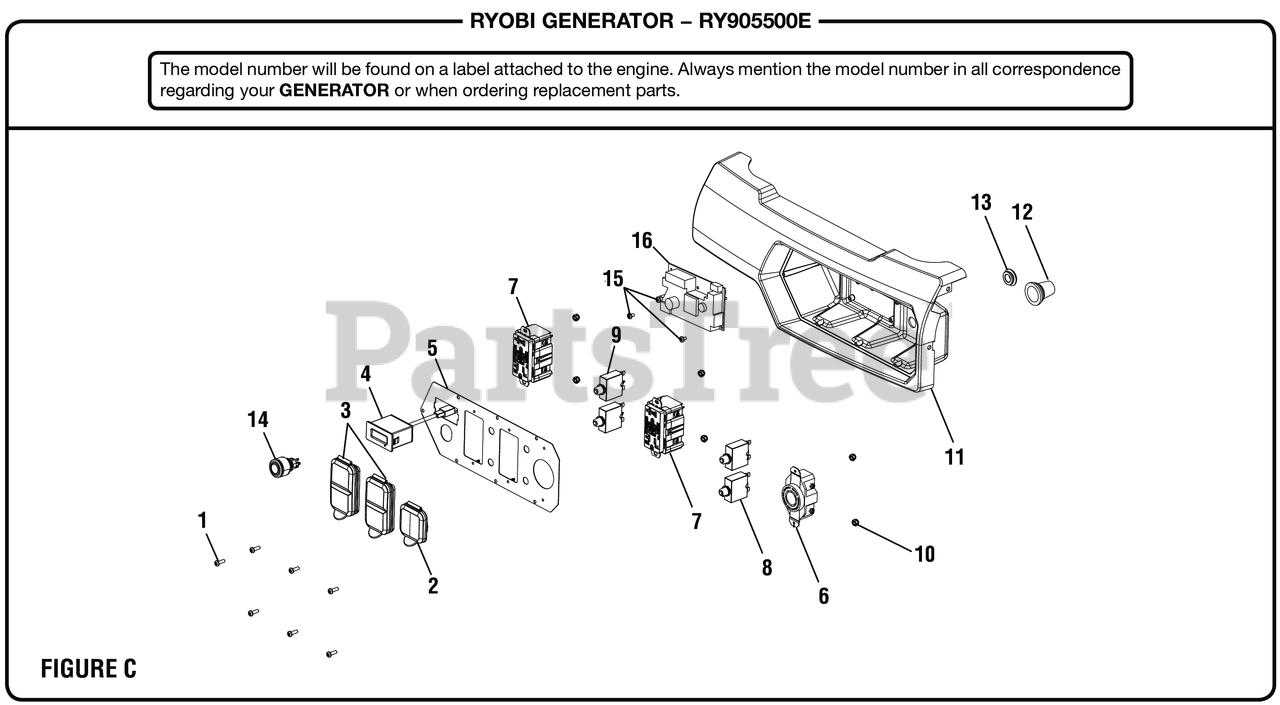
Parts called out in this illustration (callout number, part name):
1	Screw (#8-18 x 1/2 in., T20 Torx Pan Hd.)
2	240 Volt ReceptacleRain Cover
3	120 Volt Receptacle Rain Cover
4	Digital Display
5	Front Panel
6	Twist Lock Recepticle (120/240 Volt, 30 Amp, L14-30)
7	Duplex Receptacle (120 Volt)
8	Circuit Breaker (25 Amp)
9	Circuit Breaker (20 Amp, 125 Volt)
10	Lock Nut (M4)
11	Control Box (Back Panel)
12	Wiring Rubber Boot
14	Engine Start Push Switch
15	Screw (M3 x 5 mm, T10 Torx Pan Hd.)
16	Battery Charger
